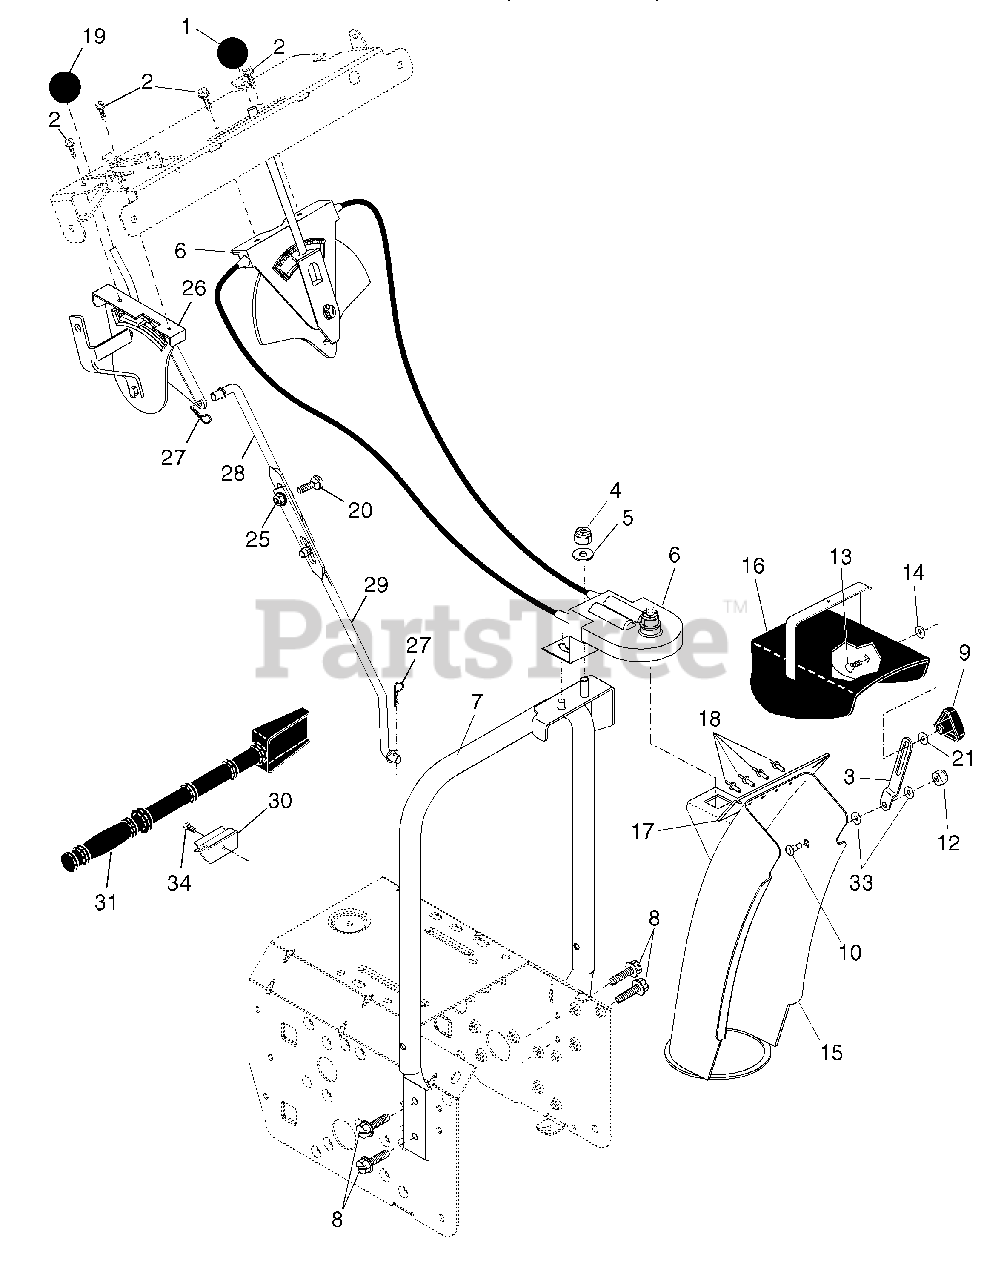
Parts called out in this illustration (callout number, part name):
1	Knob, Lever
2	Screw #10-24 x 5/8
3	Strap, Slotted
4	Nut, Lock 3/8-16
5	Washer, Flat 3/8
6	Control Assembly, Chute Rotater
7	Support, Pivot
8	Screw, Hex Head 5/16-18 x 3/4
9	Knob, Deflector
10	Bolt, Shoulder
12	Nut, Lock 1/4-20
13	Bolt, Carriage 5/16-18
14	Washer, Nylon, Friction
15	Chute Assembly
16	Deflector Assembly
17	Seal, Deflector
18	Rivet, Blind
19	Knob, Speed Control Lever
20	Bolt, Carriage 5/16-18 x 3/4
21	Washer, Flat 5/16
25	Nut, Lock 5/16-18
26	Lever Assembly, Speed Control
27	Retainer, Hairpin
28	Rod, Upper, Speed Control
29	Rod, Lower, Speed Control
30	Clamp, Clean-Out Tool
31	Tool, Clean-Out
33	Washer, Nylon, Friction
34	Screw, Hi-Lo Thread
